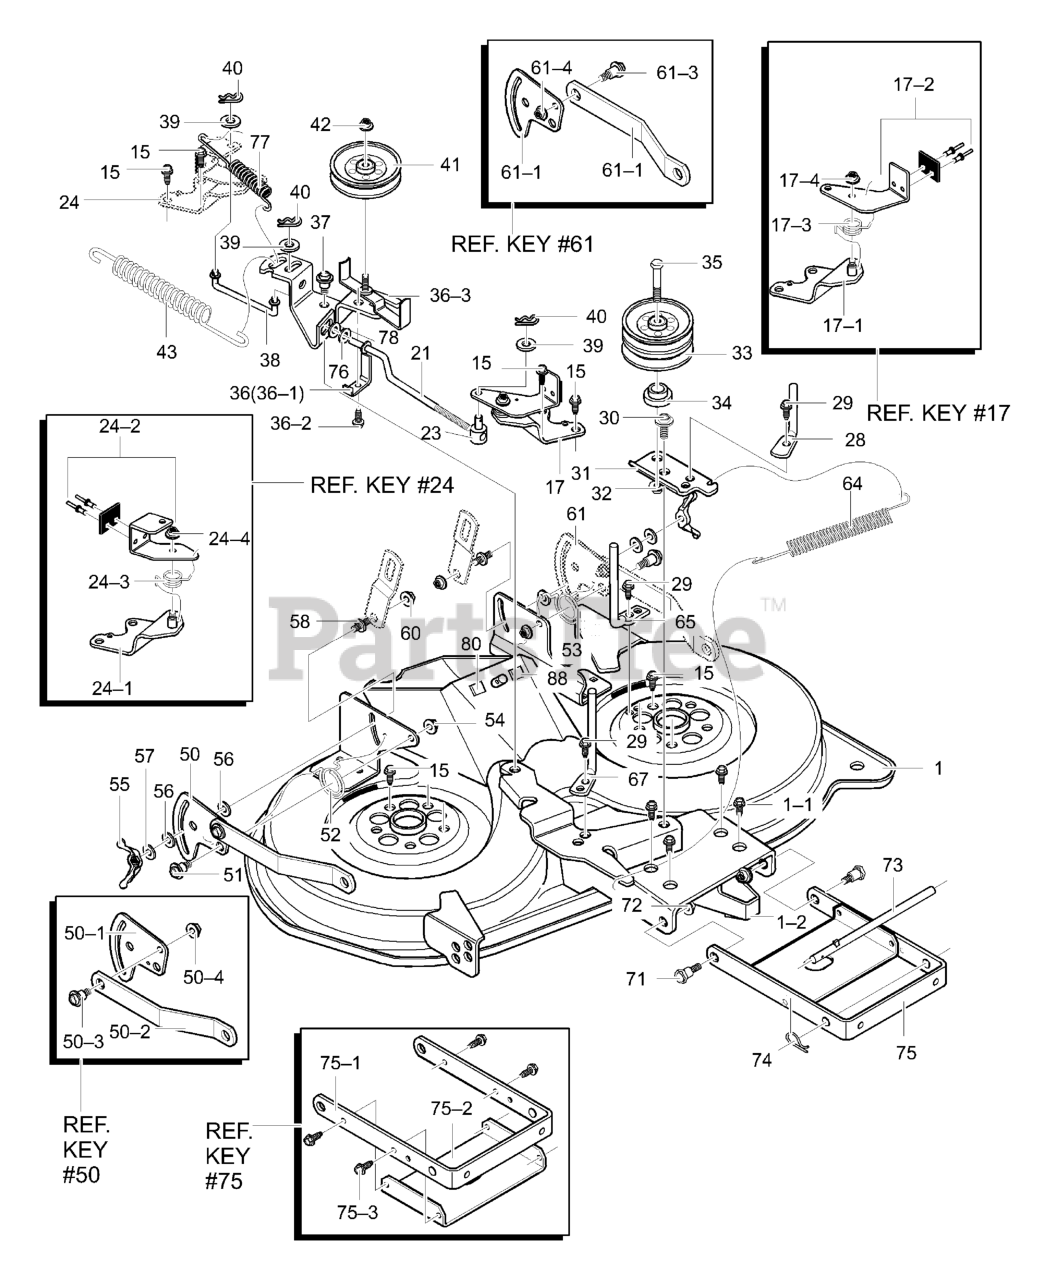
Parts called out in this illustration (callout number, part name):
1	Housing, 40" Deck
17	Brake Arm Assembly LH
17-1	Brake Support Assembly LH
17-2	Brake Arm
17-3	Spring, Torsion
17-4	Nut, 5/16-18
21	Link, Brake LH
23	Nut, Adjusting
24	Brake Arm Assembly RH
24-1	Brake Support RH
24-2	Brake Arm RH
24-3	Spring, Torsion
24-4	Nut, 5/16-18
28	Belt Guide
29	Screw, 5/16-18 x 0.50
30	Bolt, Shoulder
31	Arm, Double Idler
32	Nut, 3/8-16
33	Pulley, Idler Double Vee
35	Screw, 3/8-16 x 3.00
36	Idler Arm Assembly
36-1	Spring - Belt Guide
36-2	Screw, 1/4-20x.50
36-3	Idler Arm
37	Bolt, Shoulder
38	Link, Brake RH
39	Washer, Flat
40	Hair Pin
41	Pulley, Idler
42	Nut, 3/8-16
43	Spring, Extension
50	Assy, Plate,Rear Sus Bkt RH
50-1	Plate-Suspension
50-2	Suspension Bracket Rear
50-3	Bolt, Shoulder
50-4	Nut, 3/8-16
51	Bolt, Shoulder
52	Spring, Torsion RH
53	Spring, Torsion LH
54	Nut, 3/8-16
55	Wingnut, 5/16-18
56	Pad, Friction
57	Washer
58	Pin, Hanger
60	Nut, 3/8-16
61	Assy., Plate Rear Sus Brkt., LH
61-1	Plate-Suspension
61-2	Suspension Bracket, Rear
61-3	Bolt, Shoulder
61-4	Nut, 3/8-16
64	Spring, Extension
65	Belt Guide
67	Belt Guide
71	Shoulder Bolt
72	Nut, 3/8-16
73	Rod, Hanger
74	Hair Pin
75	Assembly, Bracket & Stiffener
75-1	Bracket, Front Suspension
75-2	Stiffener
75-3	Screw, 5/16-18 x .75
76	Flatwasher
77	Spring, Extension
78	Washer, Flat
80	Pad, Adhesive
